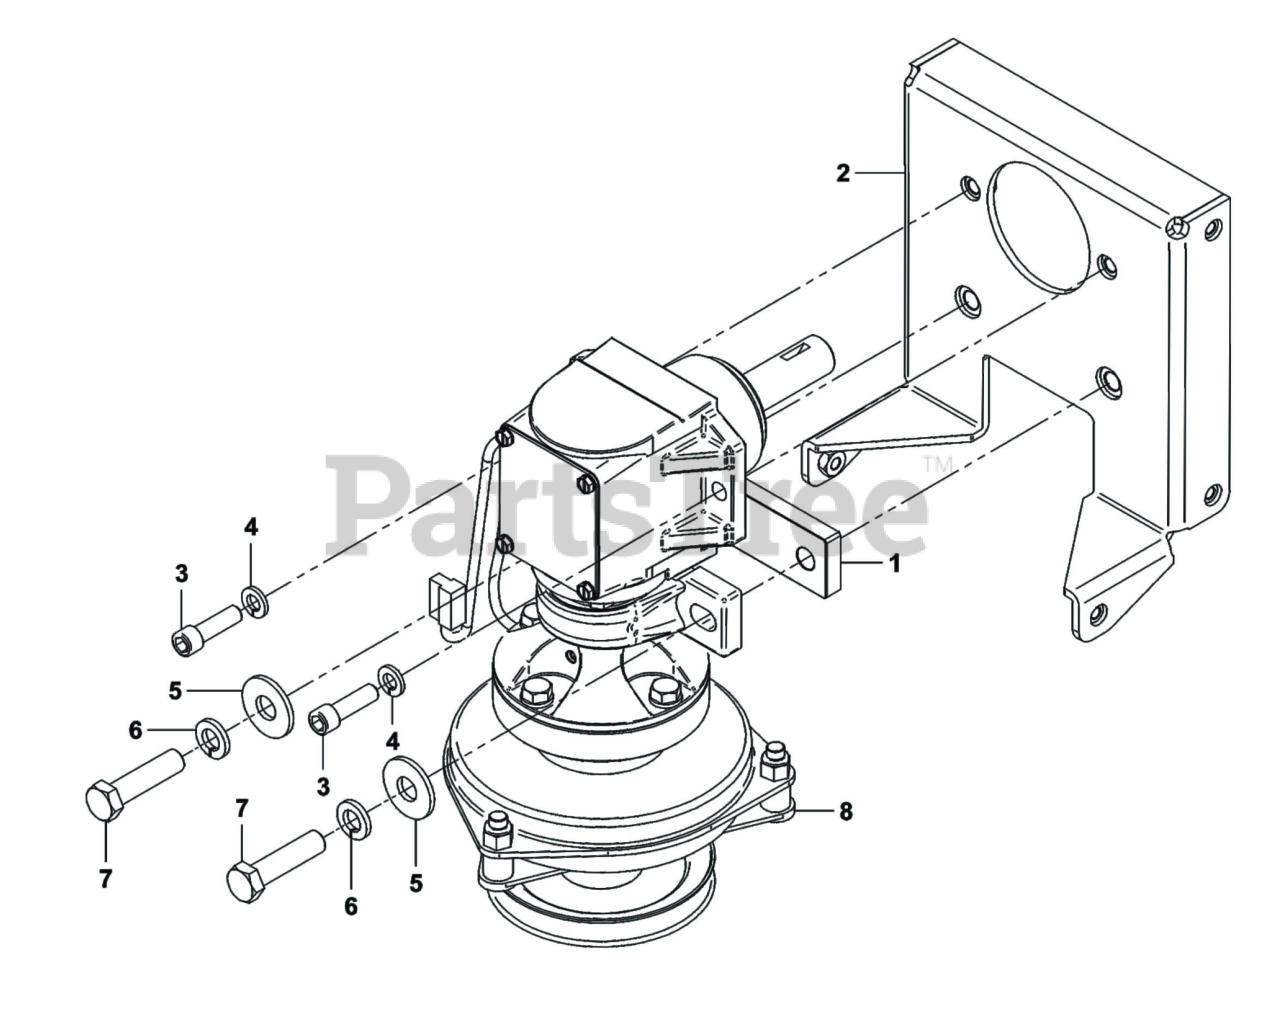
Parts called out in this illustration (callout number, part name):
1	SPACER PLATE
2	DRIVE MOUNT ASSEMBLY
3	SCREW 3/8"-16 X 1.25"
4	LOCK WASHER 3/8
5	FLAT WASHER 1/2"
6	LOCK WASHER 1/2"
7	SCREW 1/2"-13 X 2"
